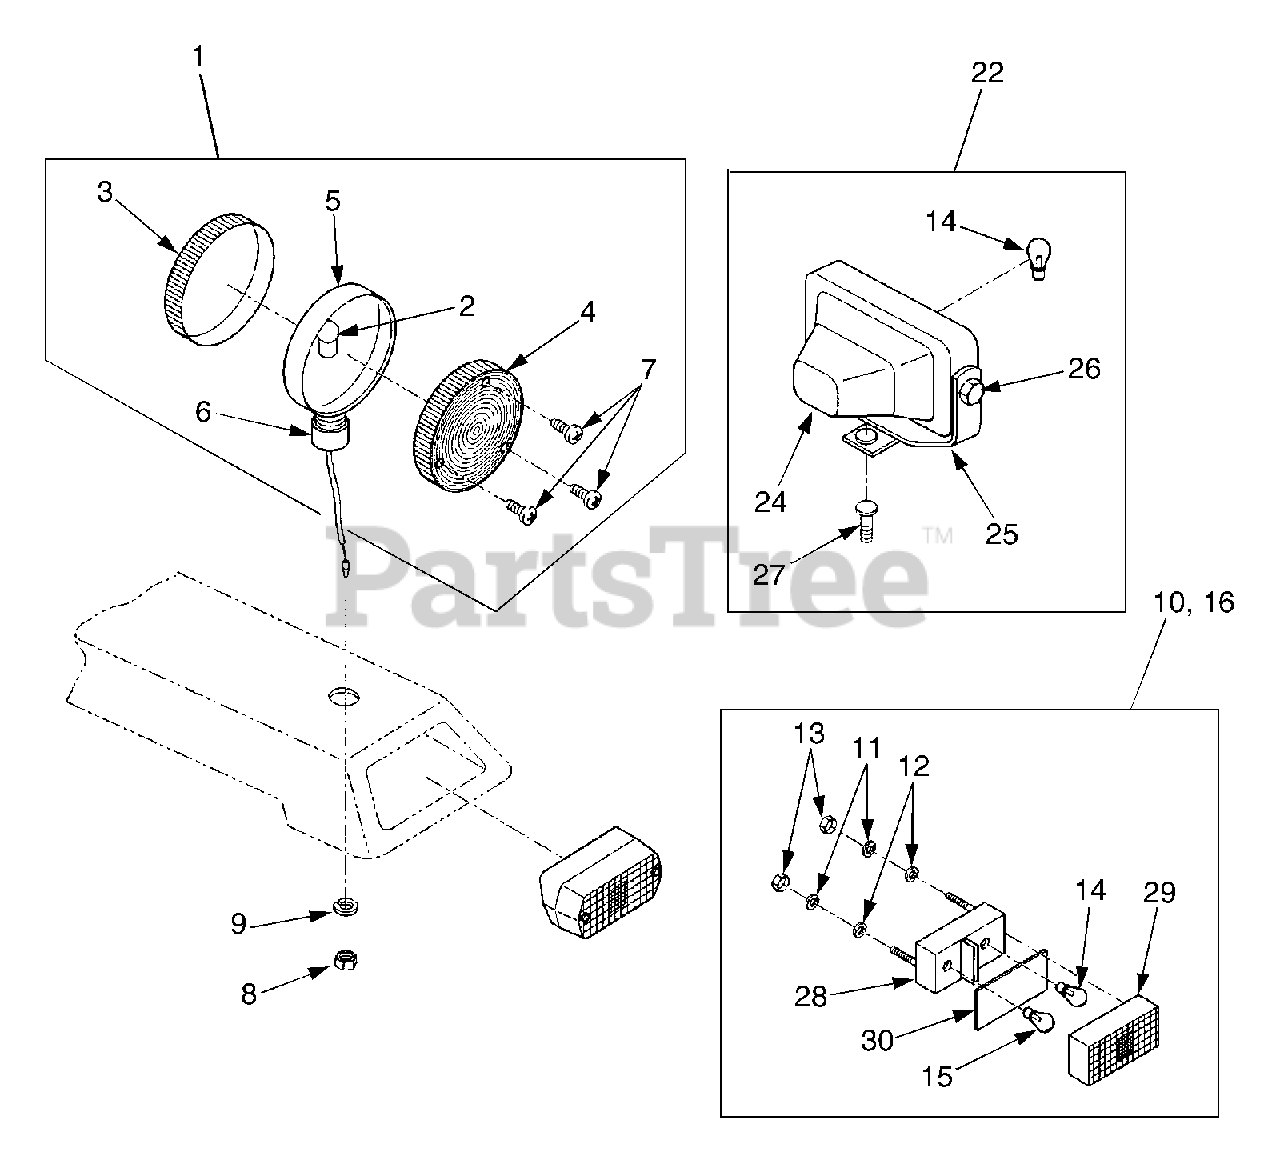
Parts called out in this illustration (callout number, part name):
1	Lamp, Hazard
9	Washer, Spring
10	Reflector Amp Ass'y (LH)
11	Washer, Plain
12	Washer, Spring
16	Reflector Amp Ass'y (RH)
22	Working Lamp Ass'y
